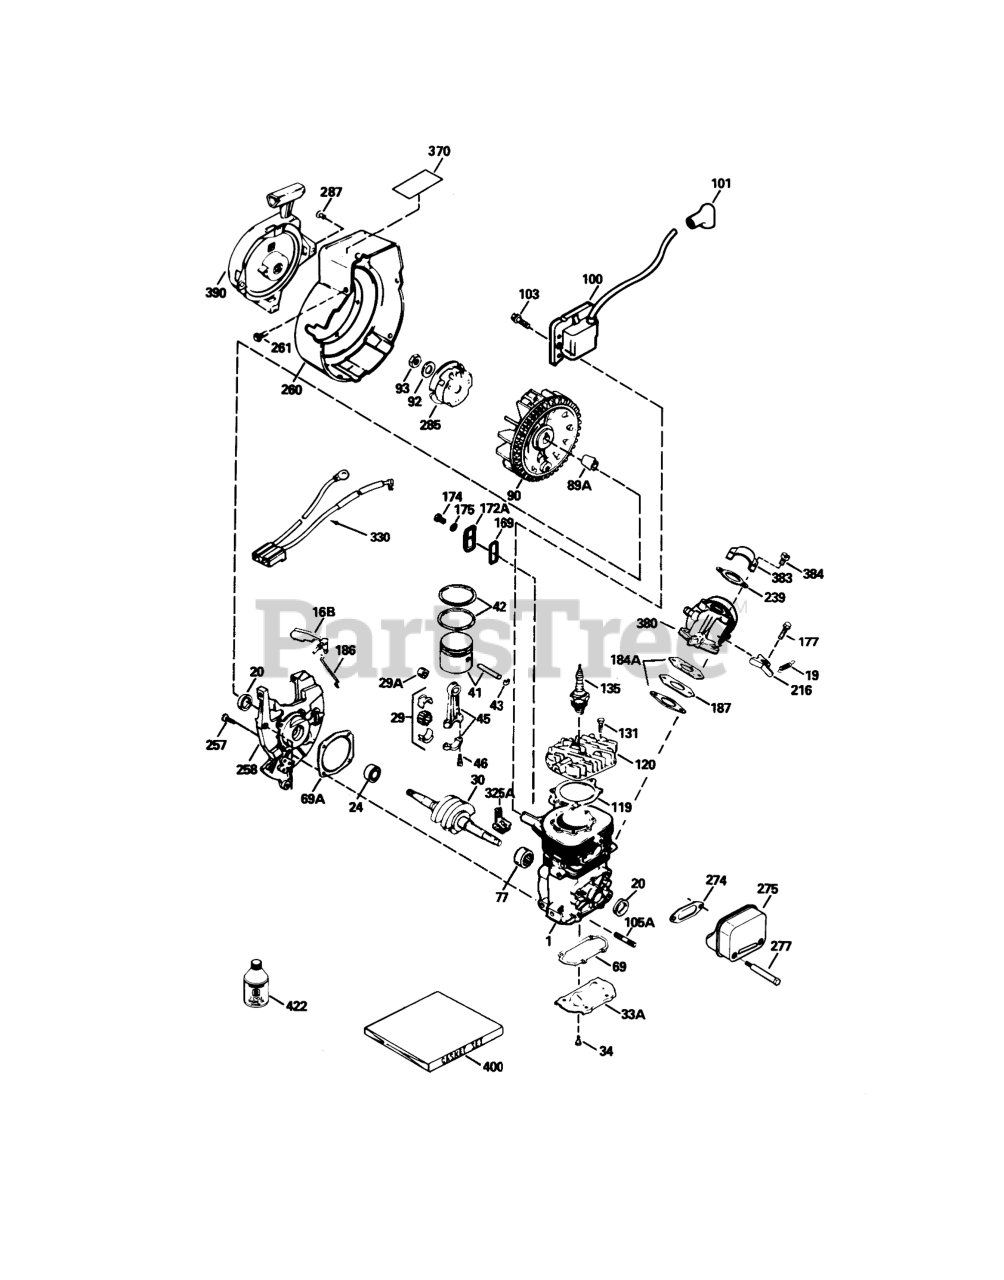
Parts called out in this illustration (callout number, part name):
1	Block Ass-y-Cylinder (Order short block if replacement is required)
16B	Vane-Air
19	Spring-Extention
20	Seal-Oil
24	Bearing-Ball
29	Needle Bearing and Liner Set (37 Needles)
29A	Bearing-Cartridge
30	Crankshaft
33A	Plate-Cover
34	Screw (T-25, 10-24 x 1/2)
41	Piston & Pin Ass-y (Incl. ref. #43)
42	Ring Set
43	Ring-Retaning
45	Rod Ass-y-Connecting (Incl. ref. #29, 29A & 46)
46	Bolt-Rod, Connecting
69	Gasket-Plate, Cover
69A	Gasket-Cover, Cylinder
77	Bearing-Cartridge
89A	Blade (20 inch)
90	Flywheel
92	Washer-Belleville
93	Nut-Flywheel
100	Solid State
101	Cover-Spark Plug
103	Screw
119	Gasket-Head, Cylinder
120	Head-Cylinder
131	Screw (T-30, 1/4-20 x 3/4)
135	Spark Plug-Resistor (R C J 8Y)
169	Cover-Compression, Release
172A	Comp. Release Cover
174	Screw (T-25, 10-24 x 1/2)
177	Screw (5/32 Allen, 1/4-20 x 1)
184A	Gasket-Carburetor
186	Link-Governor
216	Lever-Adjusting, Rpm
239	Gasket-Cleaner, Air
257	Screw (T-30, 1/4-20 x 5/8)
258	Base Ass-y-Blower Housing (Incl ref. #20)
260	Housing-Blower
261	Screw (1/4-20 x 1/2)
274	Gasket-Exhaust
275	Muffler
277	Screw (1/4-20 x 2-3/4)
285	Cup-Starter
287	Rivet-Pop
325A	Clip-Wire
330	Harness-Wire
370	Decal-Warning
380	Carburetor (Incl. ref. #184A)
383	Baffle-Carburetor
390	Starter-Rewind
400	Gasket Set
422	2-Cycle Oil (8oz)
